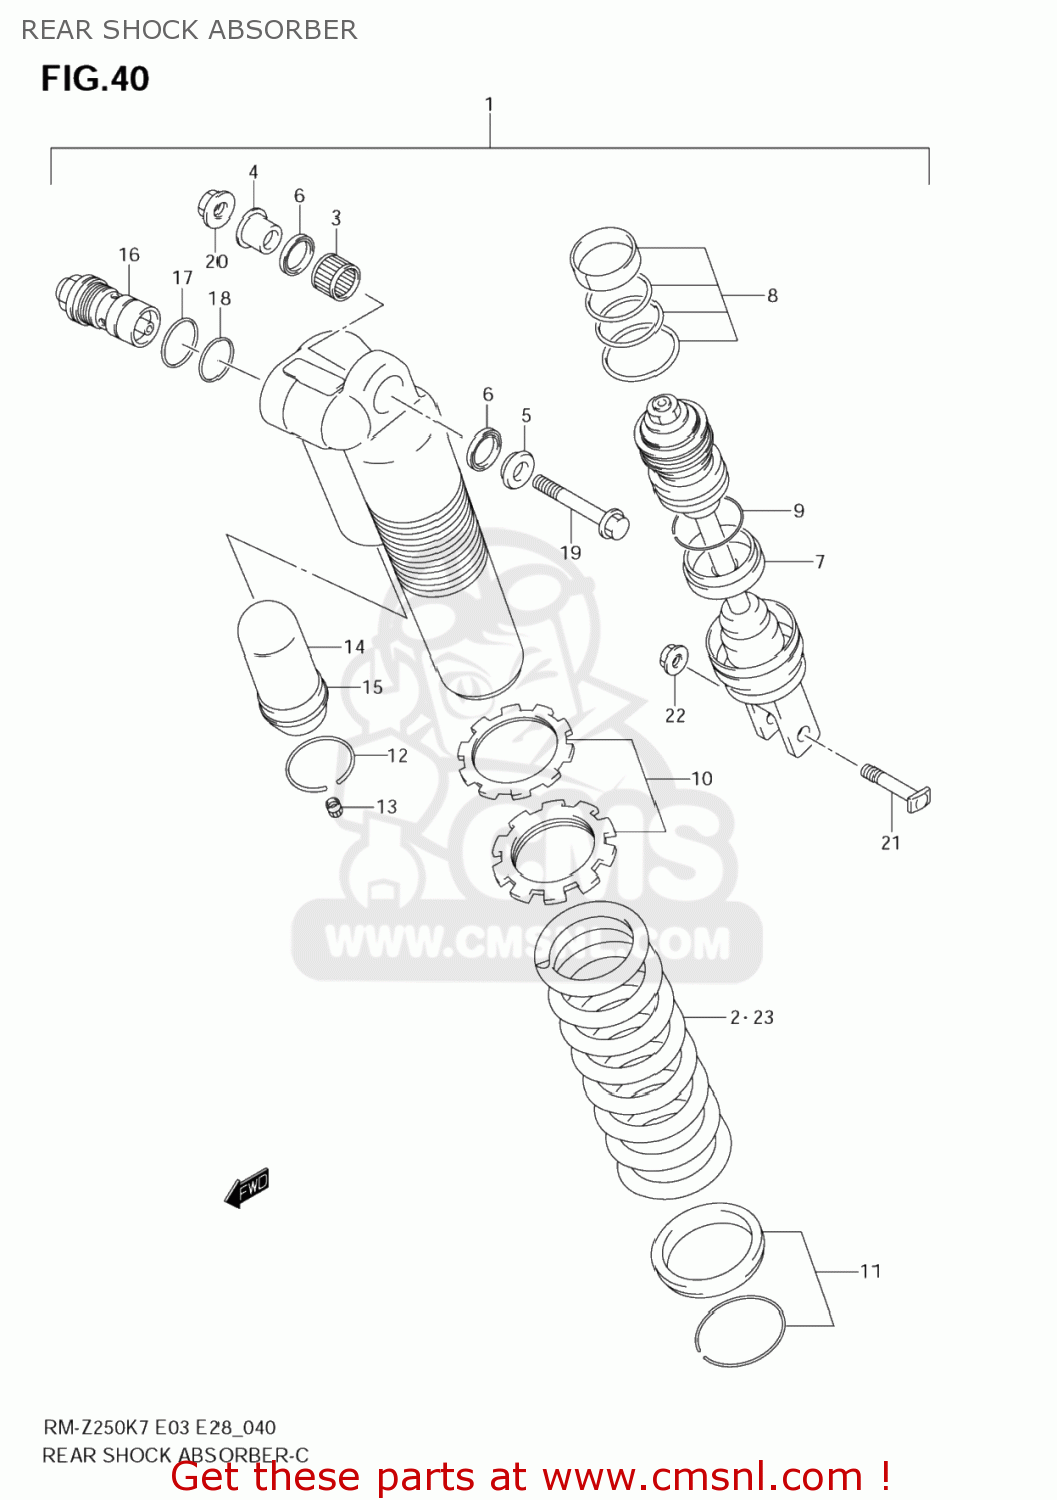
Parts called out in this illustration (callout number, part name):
1	ABSORBER ASSY,RR SHOCK
2	SPRING,RR(K=5.4)
3	BEARING(16X22X12)
4	SPACER,UPPER BRG,R
5	SPACER,UPPER BRG,L
6	SEAL,OIL(16X22X2.5)
7	SPRING
8	O RING SET
9	RING,STOPPER
10	ADJUSTER SET
11	SPRING SEAT SET
12	RING,STOPPER
13	CAP,AIR VALVE
14	BLADDER
15	CAP,CHAMBER
16	BOLT
17	O RING
18	O RING
19	BOLT(10X60)
20	NUT
21	BOLT,RR SHOCK ABSORBER LWR
22	NUT
23	SPRING(K:5.0)
